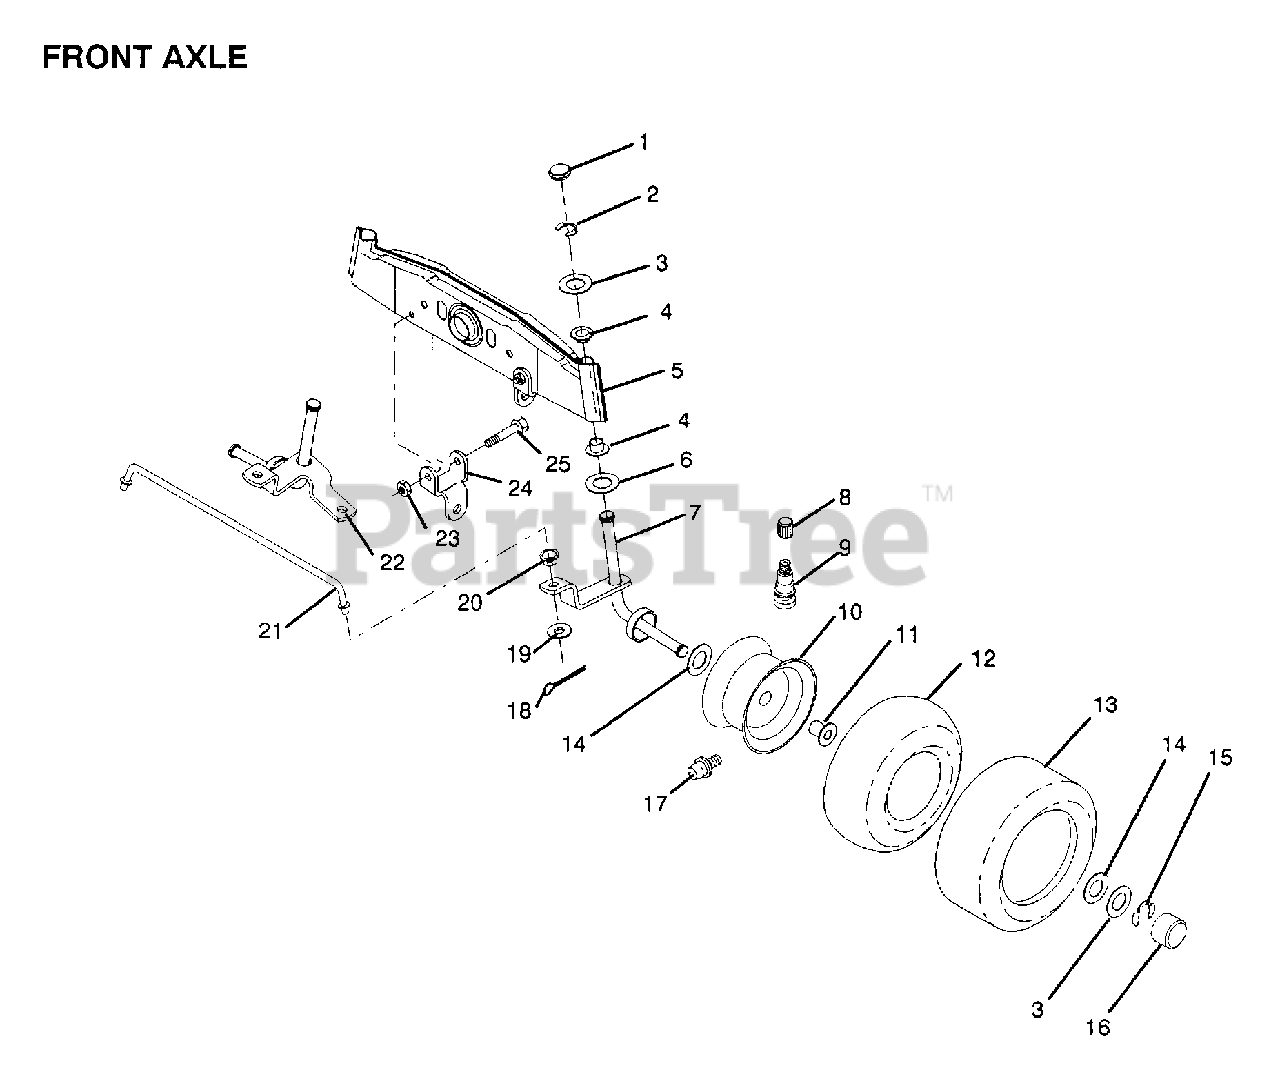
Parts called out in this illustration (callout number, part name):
1	CAP
2	RING
3	WASHER
4	NYLINER
5	AXLE FRONT
6	WASHER .T
7	SPINDLE RH
8	VALVE CAP
9	VALVE STEM LT
11	"FLANGE, BEARING"
12	TUBE.5.3/4.5/6
13	TIRE
14	WASHER
15	RING
16	HUB CAP
17	FITTING LT
18	COTTER PIN
19	WASHER
20	BUSHING.DRAGLINK
21	ROD TIE
22	SPINDLE LH
24	"BRKT,FRONT STAB"
25	BOLT
